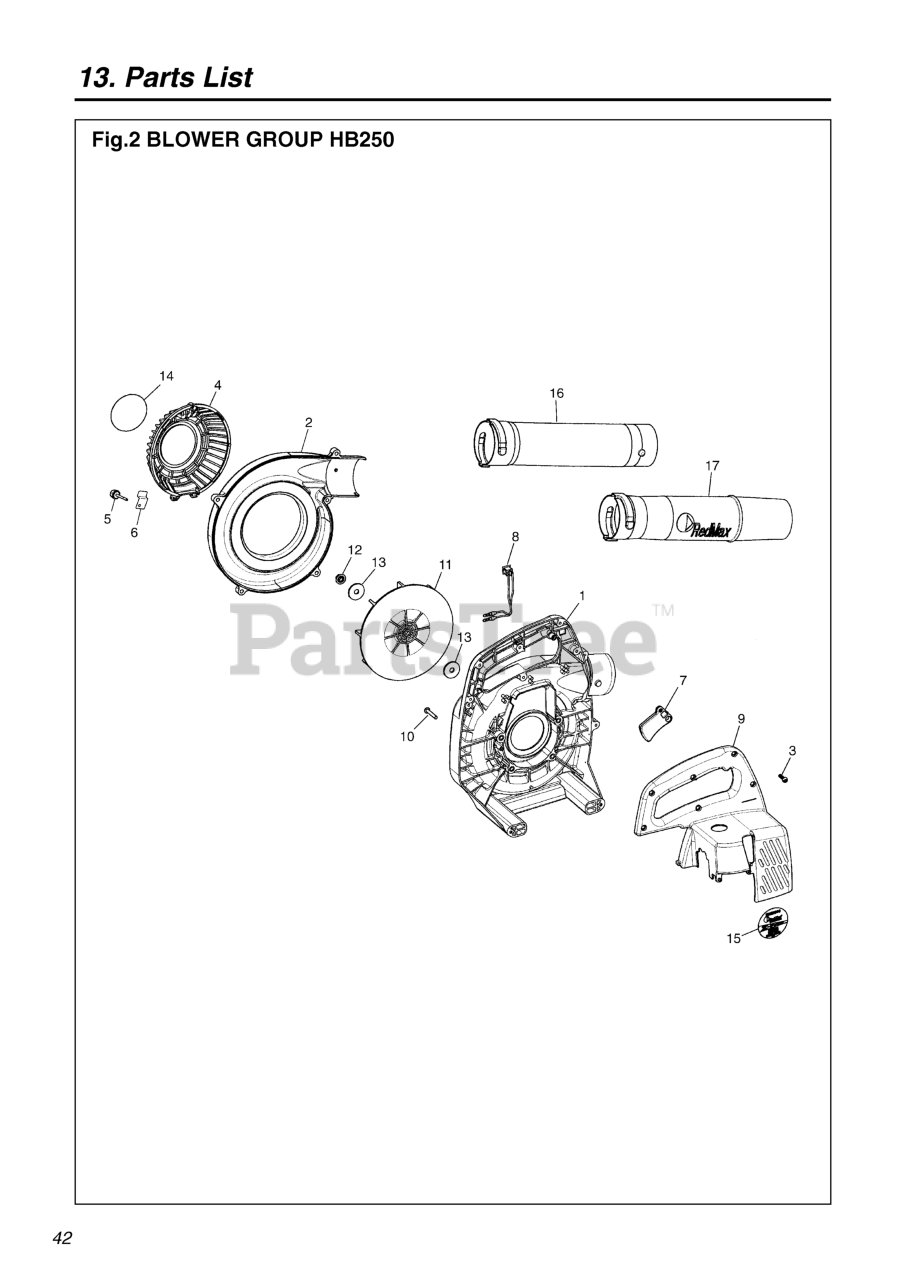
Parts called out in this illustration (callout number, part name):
1	VOLUTE CASE (RPLS. 6811-11110)
2	VOLUTE COVER
3	SCREW, TORX (RPLS T4970-52001)
4	GUARD
5	SCREW
7	LEVER
8	SWITCH
9	ENGINE COVER
10	SCREW
11	FAN
13	WASHER
14	LABEL, CAUTION
15	LABEL, RECOIL
16	PIPE, STRAIGHT
17	PIPE, END
